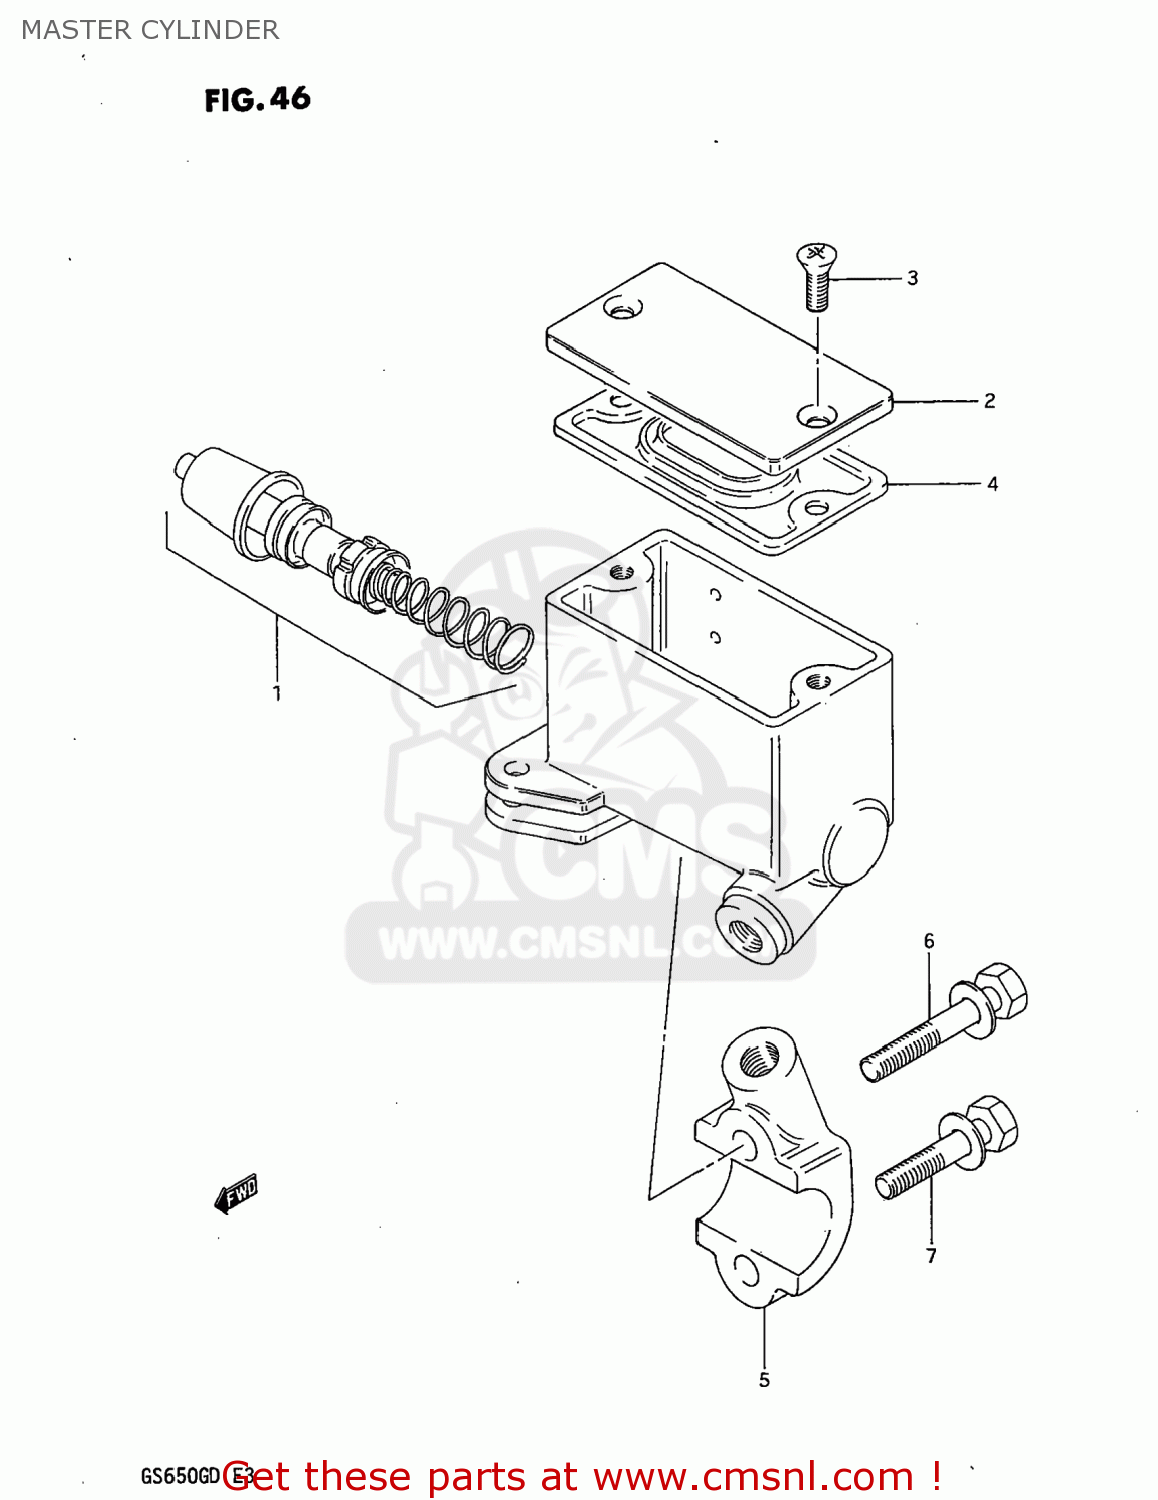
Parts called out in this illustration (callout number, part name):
1	PISTON & CUP SET
2	CAP,MASTER CYLINDER,REAR
3	SCREW,RESERVOIR CAP
4	DIAPHRAGM,MASTER CYLINDER
5	HOLDER
6	BOLT,MASTER CYLINDER H
7	BOLT,MASTER CYLINDER H
